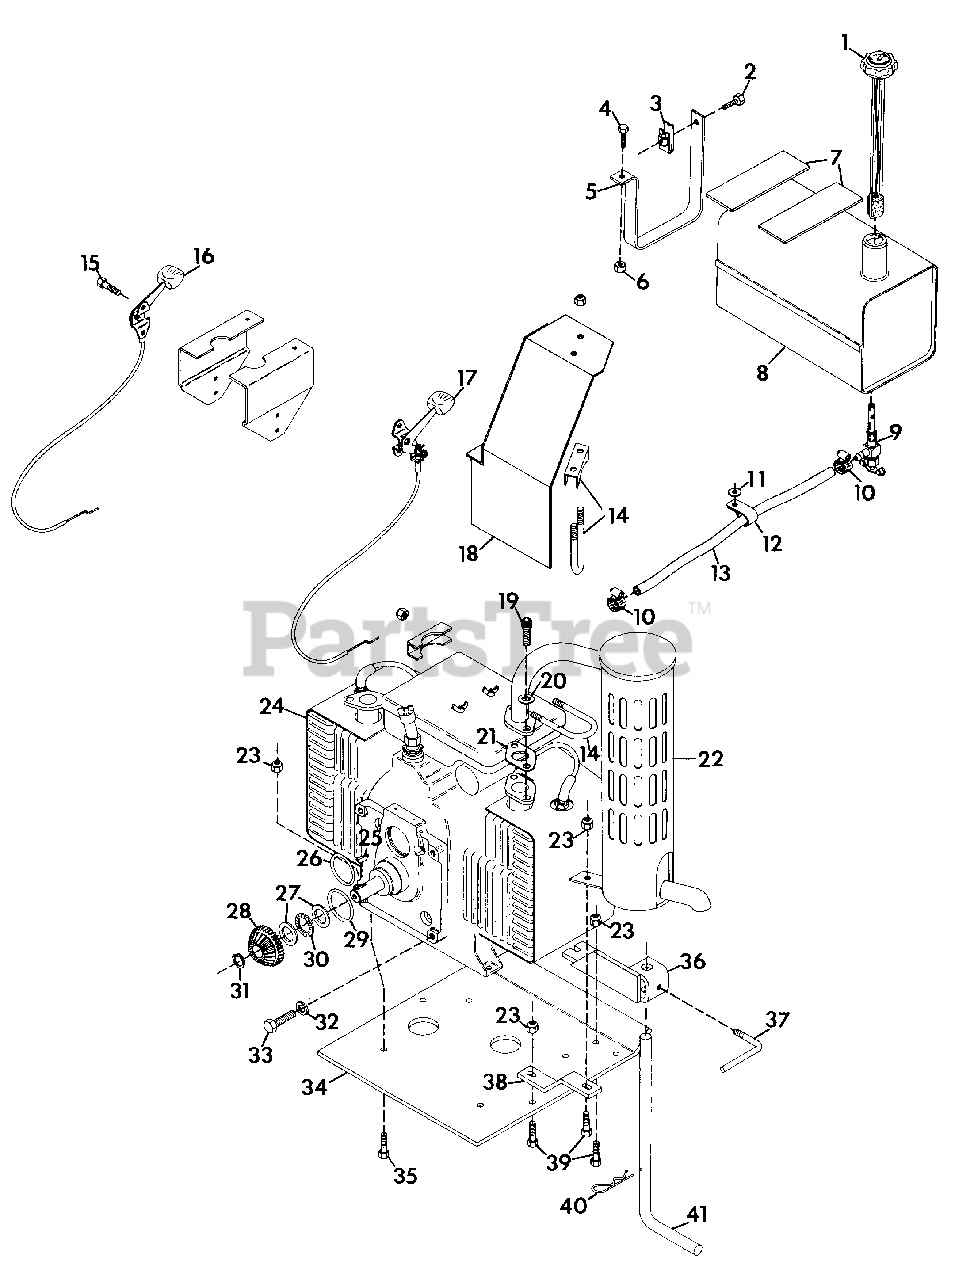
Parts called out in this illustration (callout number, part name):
1	GAUGE, FUEL
2	BOLT, HEX 5/16-18X.75
3	NUT, RETAINER
4	BOLT, HEX 5/16-18X1.25
5	STRAP, GAS TANK
6	NUT, LOCK 5/16-18
7	PAD, GAS TANK
8	TANK, FUEL
9	VALVE AND STRAINER
10	CLAMP, HOSE
11	WASHER, FLAT .344X.688X.065
12	CLAMP, NYLON
13	LINE, FUEL
14	CLAMP, MUFFLER
15	SCREW, TAPPING 10-24X.50
16	LEVER, CONTROL
17	LEVER, CONTROL
18	SHIELD, HEAT L.H.
18	SHIELD, HEAT R.H.
19	SCREW, CAP 5/16-18X.75 S/HD
20	WASHER, LOCK 5/16 REG.
21	GASKET, EXHAUST
22	MUFFLER, PRO MASTER-60 KT 17
23	NUT, LOCK 3/8-16
24	ENGINE, 17 HP ELECTRIC
24	ENGINE, 19 HP ELECTRIC
25	KEY, SQUARE .250X1.250
26	O-RING, 2.50X2.750X.125
27	RACE, BEARING THRUST 1.125X1.750X.125
28	GEAR, SPUR AND BEVEL INPUT
29	O-RING, 3.000X3.188X.094
30	BEARING, THRUST 1.127X1.740X.078
31	RING, RETAINING 1.125 SHAFT
32	WASHER, LOCK 1/2 REG.
33	BOLT, HEX 1/2-13X1.25
34	PLATE, SKID
35	BOLT, HEX 3/8-16X1.25
36	STAND, SUPPORT
37	HANDLE, ADJUSTING
38	BRACKET, MUFFLER
39	BOLT, HEX 3/8-16X1.12
40	PIN, HAIR
41	STAND, KICK
